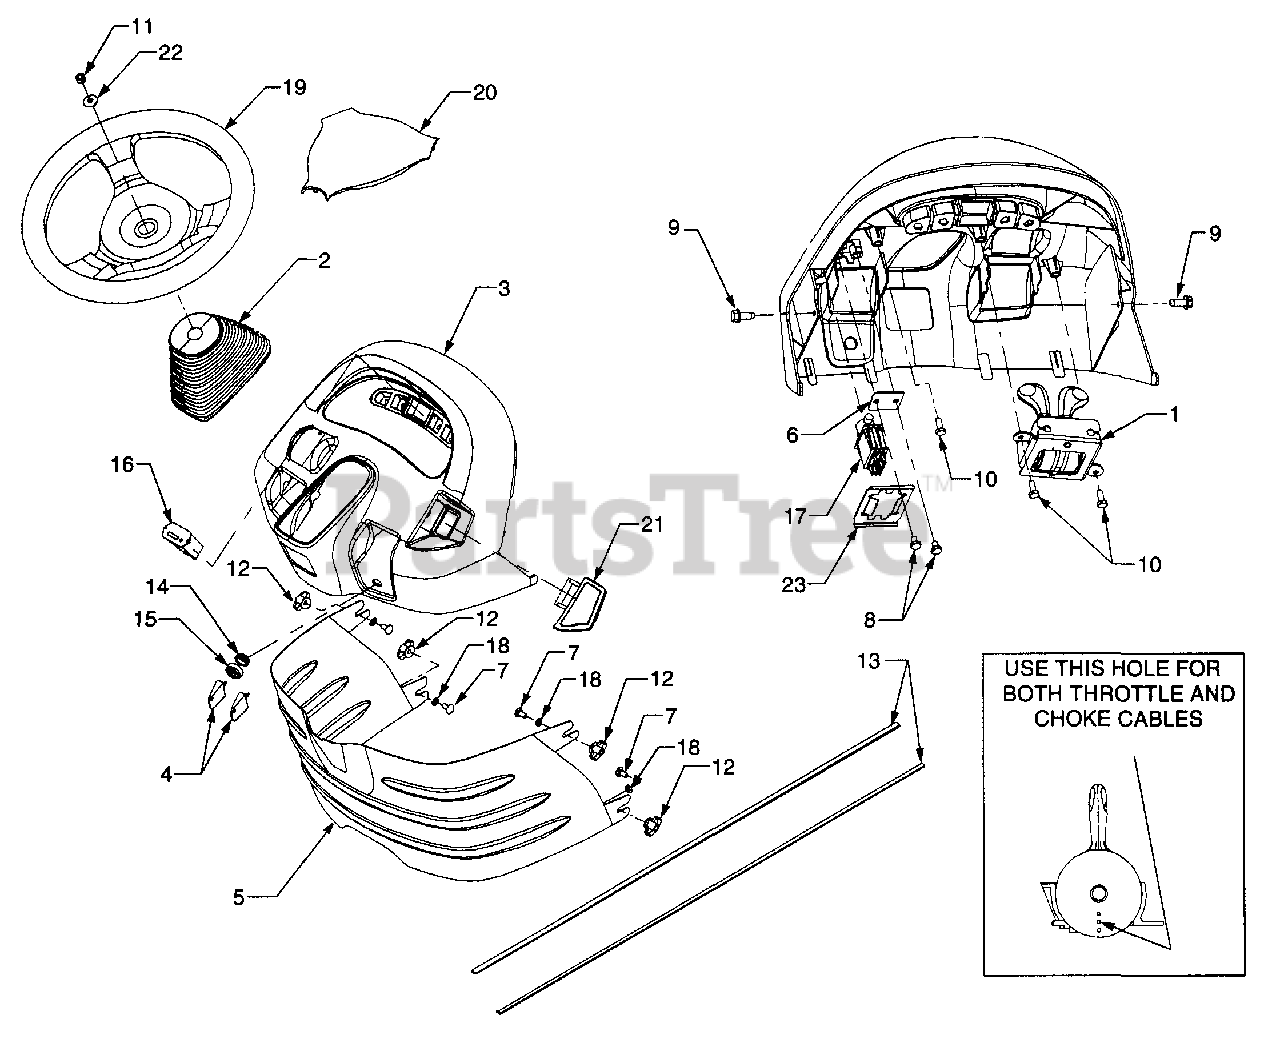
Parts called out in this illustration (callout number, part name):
1	Control Assembly, Throttle/Choke
2	Boot, Tilt Steer
3	Dash Panel
4	Key, Ignition (Set of 2)
7	Carriage Bolt, 1/4-20 x .62
8	Screw, Hex Cap 1/4-20 x .375 GR5
9	Screw, Hex Wash. Hd. Tapp 5/16-18 x .75
10	Screw, Hex Cap 1/4-20 x .50 GR5
11	Nut, Hex Lock, 5/16-24
12	Wing Nut, 1/4-20 w/Bell Washer
13	Seal, Screen
14	Nut, Ignition Switch, 5/8-32
15	Cap, Ignition Switch
16	Hour Meter
17	Switch, PTO
18	Nut, Push
19	Steering Wheel
20	Cover, Steering Wheel
21	Handle, PTO Switch
22	Washer, Belleville, .34 x .872
23	Bracket, PTO Switch Retainer
